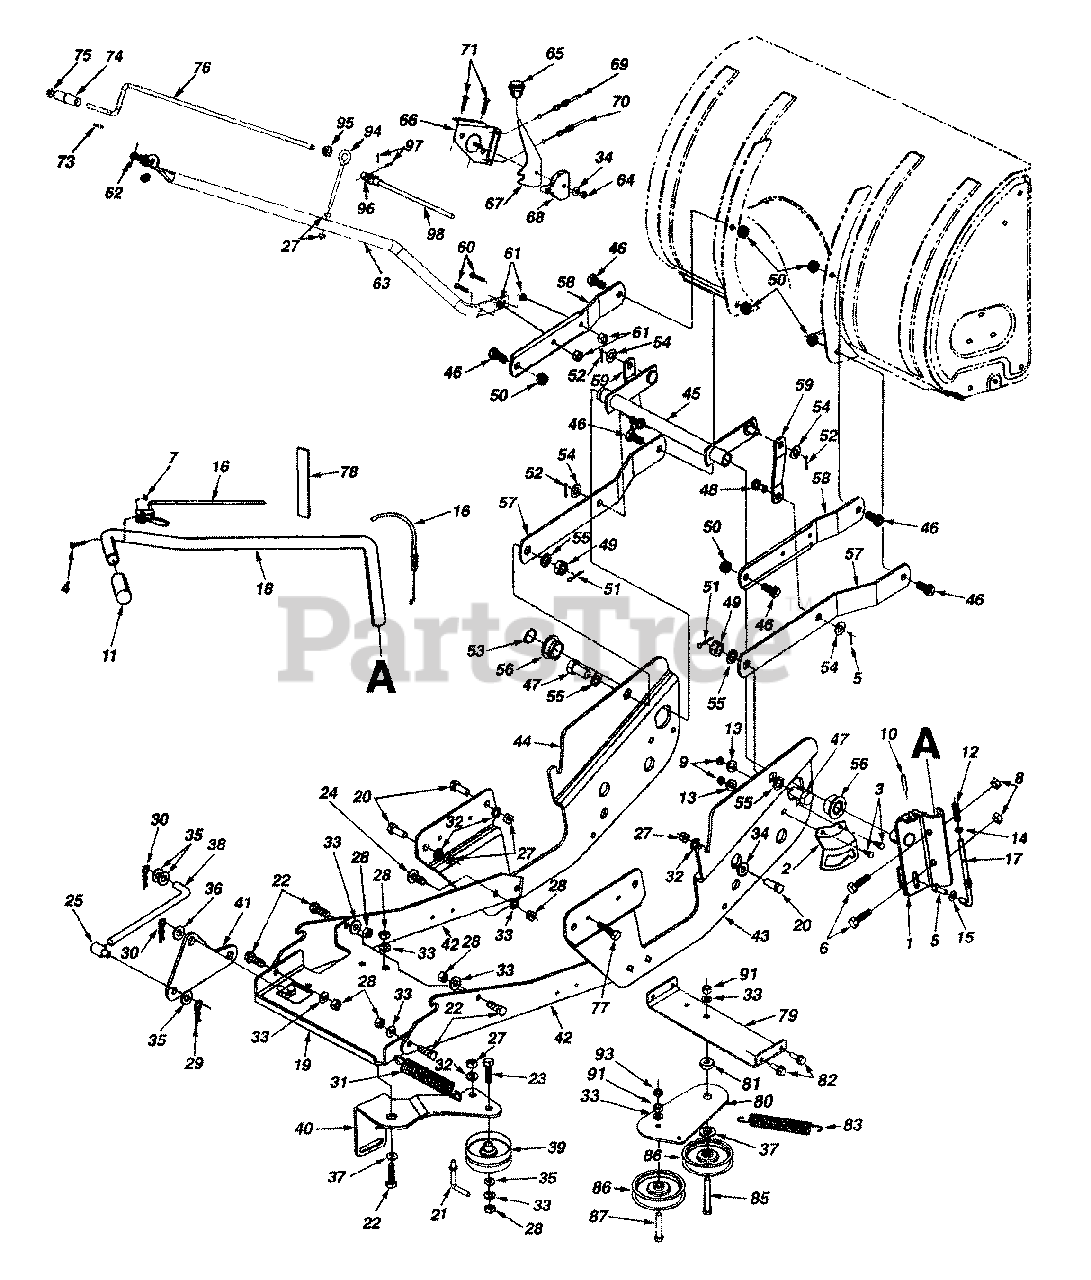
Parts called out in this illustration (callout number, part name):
4	Oval C-Sunk Scr. #10-24 x 1.36" Lg.
5	Hex Wash. Hd Scr. 5/16-18 x 87" Lg.
6	Hex Bolt 5/16-18 x 1.75" Lg
7	Flat Weld Nut #10-24 Thd
8	Hex Flange L-Nut 5/16-18 Thd.
9	Hex Nut 5/16-18 Thd. (Gr. 5)
10	Spring Pin 1.5" Lg.
12	Ext. Spring 1.75" Lg.
13	L-Wash. 5/16" I.D.
14	Fl-Wash. .385" I.D x.62" O.D.
15	Fl-Wash. .194" I.D. x.62" O.D.
16	Lift Cable
17	Lift Index Rod
22	Hex Bolt 3/8-16 x 1" Lg.
23	Hex Bolt 3/8-16 x 2" Lg. (Gr. 5)
24	Carriage Bolt 3/8-16 x 1" Lg. (Gr. 5)
25	Ferrule 3/8-24 Thd.
27	Hex Nut 5/16-18 Thd. (Gr. 5)
28	Hex Nut 3/8-16 Thd. (Gr. 5)
29	Hairpin Clip 1.42" Lg.
30	Hairpin Clip 1.62" Lg.
31	Ext Spring 5.5" Lg.
32	L-Wash. 5/16" I.D.
33	L-Wash. 3/8" I.D.
34	Bell-Wash. .345" I.D. x.88" O.D.
35	Fl-Wash. .406" I.D. x.875" O.D.
36	Fl-Wash. .531" I.D. x 1" O.D.
37	Shoulder Spacer
38	Adj. Clutch Control Rod
39	Idler Pulley
47	Hex Bolt 5/8-18 x 1.25" Lg. (Gr. 5)
48	Lift Bracket Pin
49	Hex Slotted Nut 5/8-18 Thd.
50	Hex Cent. L-Nut 1/2-13 Thd.
51	Cotter Pin 1.25" Lg
52	Cotter Pin 75" Lg.
54	Fl-Wash. .51" I.D. x 1" O.D.
55	Fl-Wash. 5/8" I.D. x 1" O.D.
56	Flange Bearing w/Flats
61	Hex Flange L-Nut 5/16-18 Thd.
62	Plastic Bushing
64	Hex Jam Nut 5/16-18 Thd.
65	Knob
68	Cable Guide
69	Chute Control Cable w/Clip
70	Chute Control Cable
71	Carriage Bolt 5/16-18 x 1 5" Lg.
73	Roll Pin .63" Lg
74	Chute Crank Knob
75	Push Cap 3/8" Rod
76	Upper Chute Crank Rod
77	Hex Wash. Hd Tap Scr 1/4-20 x .75" Lg.
82	Hex Wash Hd. Tap Scr. 5/16-18
83	Extension Spring
85	Hex Bolt 3/8-24 x 2 25" Lg.
86	Flat Idler
91	Hex Nut 3/8-24 Thd.
93	Hex Jam L-Nut 3/8-24 Thd.
94	Chute Crank Eyebolt
95	Rubber Grommet
96	Joint Block Assembly
98	Lower Chute Crank
